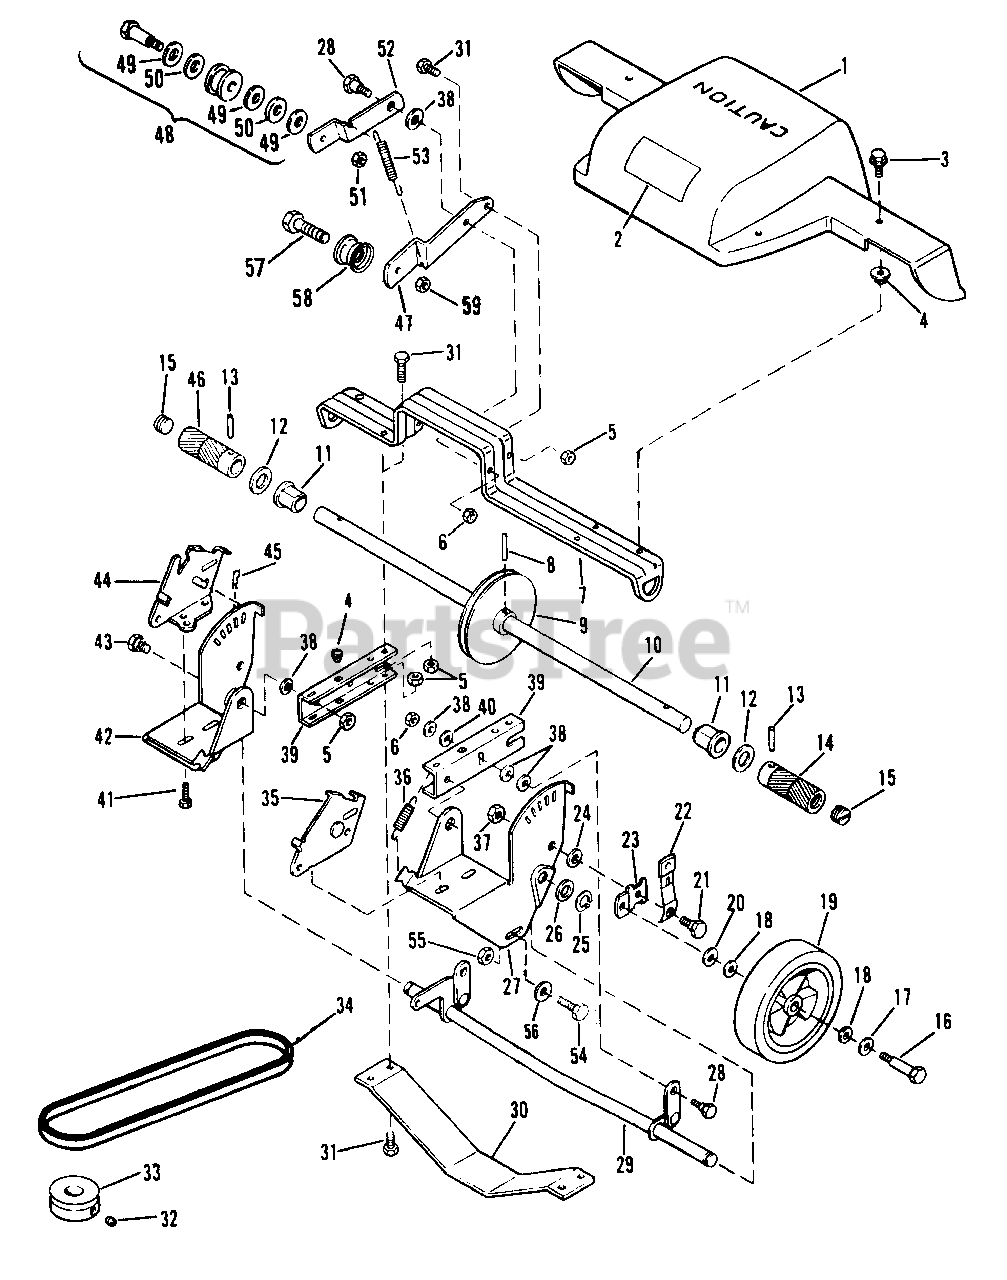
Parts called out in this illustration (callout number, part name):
1	Cover & Decal Ay.
2	Decal-Belt Inst.
3	Screw-Drive Cover
4	Grommet
5	Nut
6	Nut
7	Bracket-Bearing
8	Roll Pin
9	Pulley
10	Shaft
11	Sleeve & Bearing Ay.
12	Washer (24)
13	Pin-Spring
14	Drive Roller-Left
15	Plug
16	Bolt-Wheel
17	Washer-Wheel Bolt Head
18	Washer-Felt
19	Wheel & Tire Ay.-Rear
20	Washer-Wheel Bolt
21	Bolt-Shoulder
22	Knob & Spring Ay.
23	Bracket-Height Adj. Rear
24	Washer-Rear Ht. Adj.
25	Retaining Ring
26	Washer
27	Support Bracket-Left
28	Bolt-Shoulder
29	Clutch Shaft Assembly
30	Pulley Guard
31	Screw
32	Setscrew
33	Pulley-Engine
34	V-Belt
35	Handle Bracket & Pin Ay. L.H.
36	Spring-Neutral Return
37	Nut-Shoulder Bolt, Height Adj.
38	Washer
39	Arm-Pivot
40	Washer
41	Screw-Hdl. Brket. to Housing
42	Support Bracket-Right
43	Bolt-Shoulder
44	Handle Bracket & Pin Ay. R.H.
45	Hairpin
46	Drive Roller-Right
47	Idler Arm-Fixed
48	Idler Service Ass'y
49	Washer-Thrust
50	Washer-Felt
51	Nut
52	Idler Arm-Floating
53	Spring-Floating Idler
54	Screw
55	Nut
56	Washer
57	Screw-Idler
58	Pulley-Idler
59	Nut-Lock
